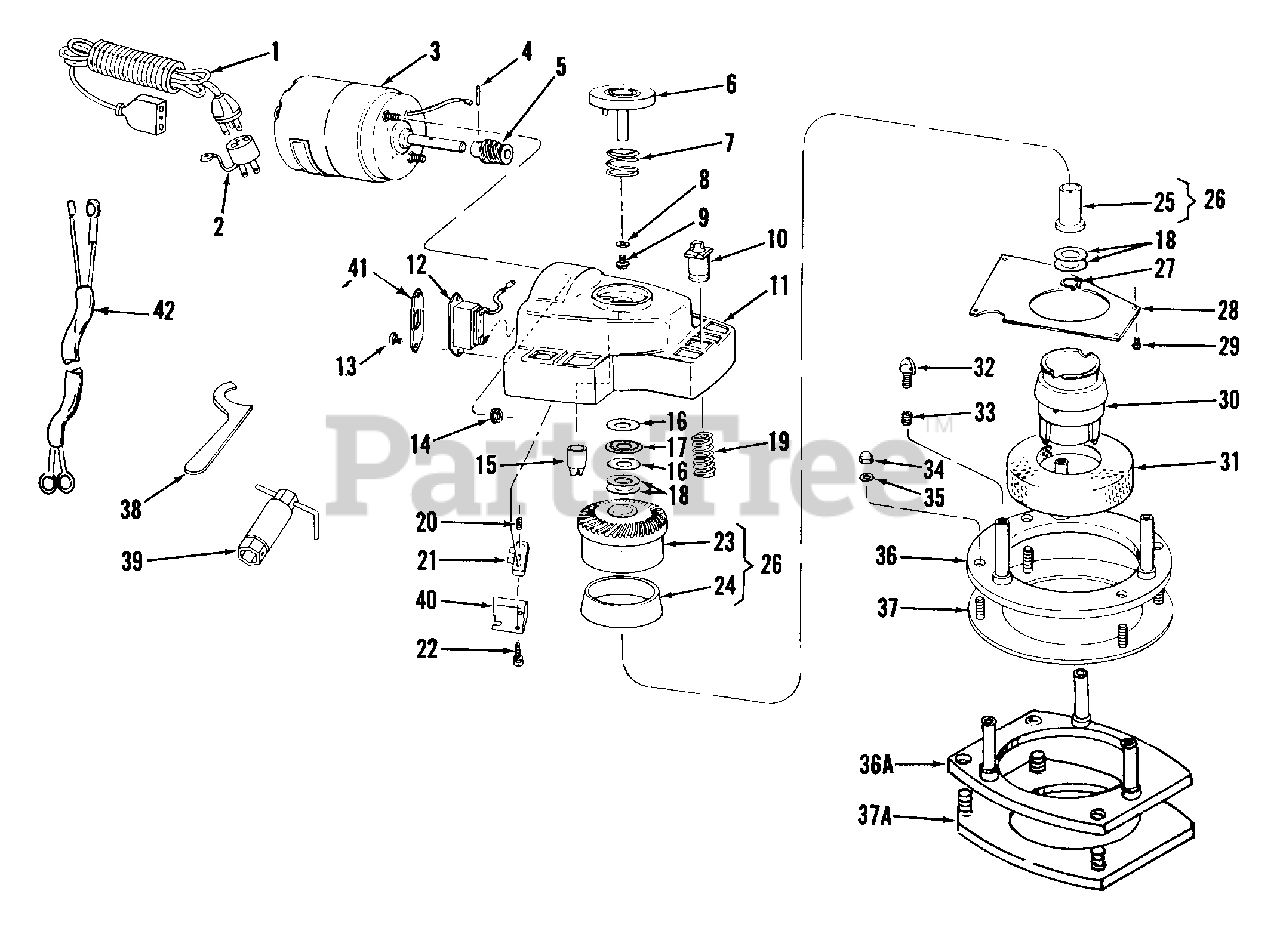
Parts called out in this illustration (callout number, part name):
3	Motor, DC electric
4	Pin, Roll
5	Gear, Pinion
6	Button, Starter switch
7	Spring, Switch return
8	Washer, Flat, No. 10
9	Screw, Rd. hd. Sems, 10-32 x 3/8
10	Bushing
11	Housing, Starter
13	Screw, Sems, 4-40 x 1/4
14	Nut & Lockwasher Assy.
15	Bearing, Pinion
16	Race, Thrust
18	Shim, Thrust
19	Spring, Guide post
20	Spring, Switch plunger
21	Switch, DC
22	Screw, Sems, No. 4-40 x 1/2
23	Gear, Driven
24	Facing, Clutch
25	Bearing
26	Cone Assy., Gear
27	Ring, Truarc
29	Screw, Sems, No. 4-40 x 1/4
32	Cap, Stud
33	Spring, Stud cap
34	Nut, Acorn
35	Lockwasher
36A	Ring, Mounting
41	Cover, Receptacle
42	Leads, Battery
